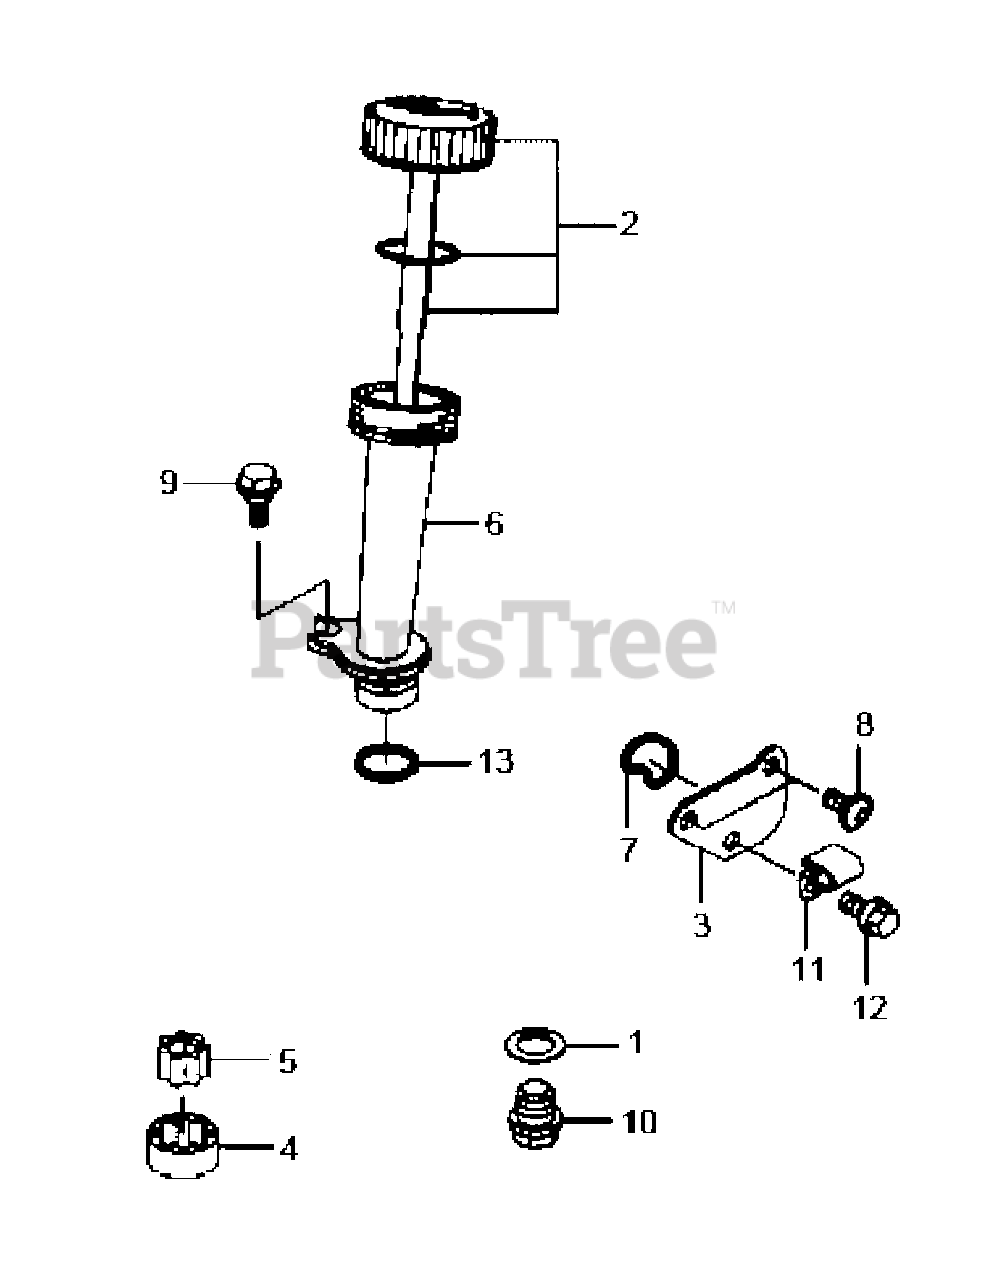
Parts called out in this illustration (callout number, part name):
1	Gasket, 12x19x1.27
2	Dipstick Cap Assy.
3	Oil Filter Cover
4	Oil Pump Rotor (Outer)
5	Oil Pump Rotor (Inner)
6	Filler Tube
8	Bolt, 6x12
12	Flanged Bolt
13	O-Ring, 16mm
